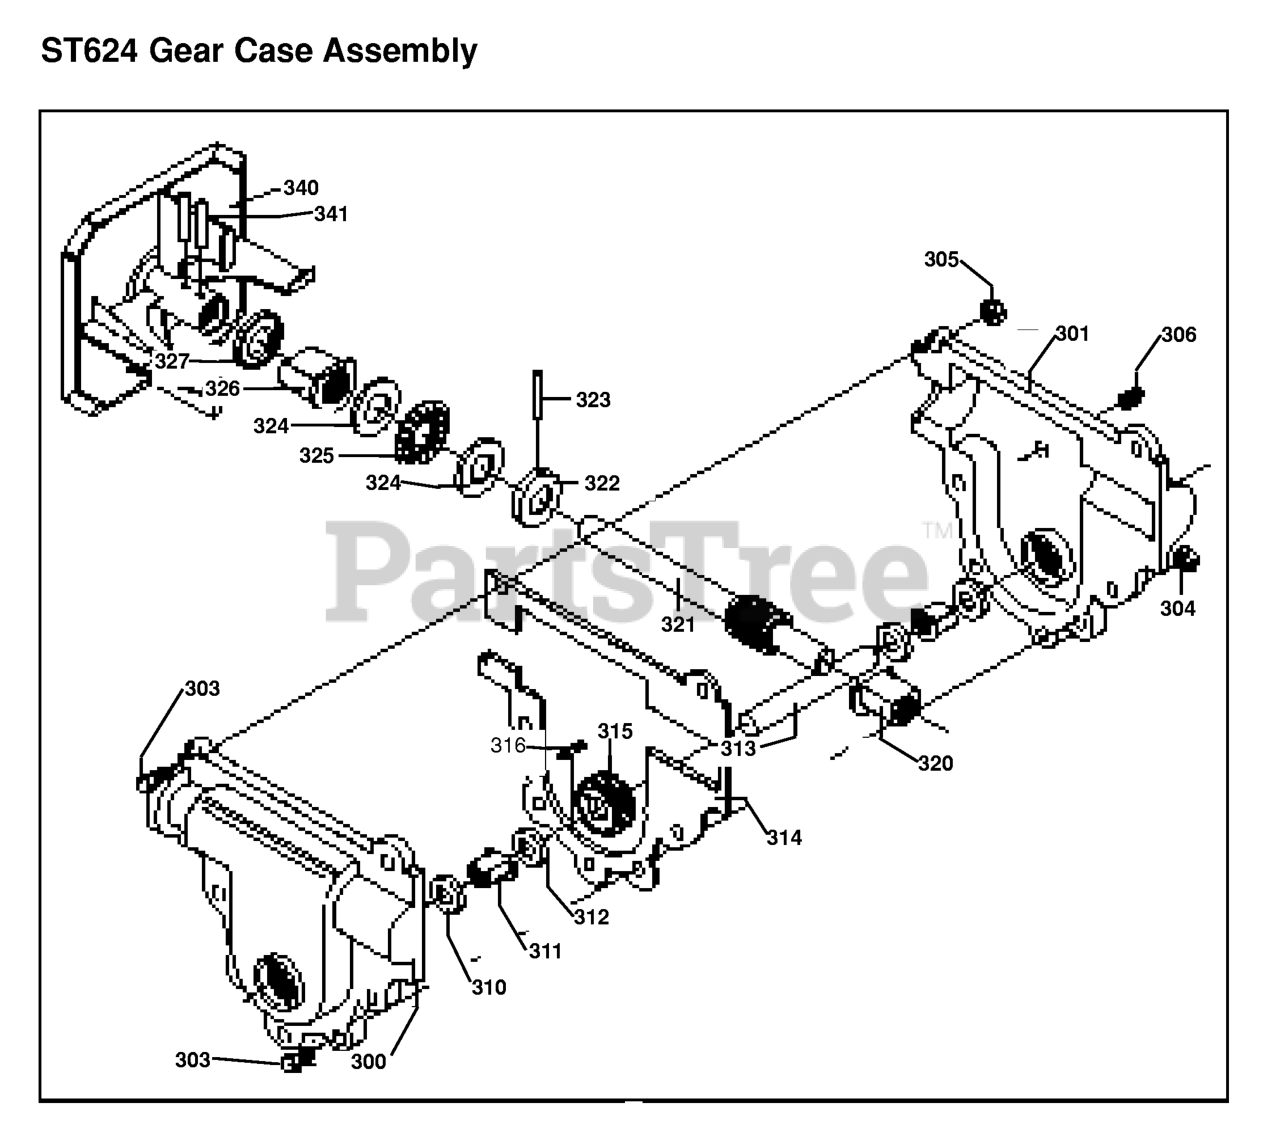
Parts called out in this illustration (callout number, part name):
300	GEAR CASE, RH
301	GEAR CASE, LH
303	SCREW, 1/4-20 X .75
304	NUT 1/4-20
305	NUT, 1/4-20 HEX KEPS
306	SCREW, 3/8-16X.50
310	SEAL, OIL, .75 X 1.19 X .25
311	BEARING, FLANGE
312	FLATWASHER
313	AUGER SHAFT
314	GASKET, GEAR CASE
315	GEAR, WORM
316	KEY, WOODRUFF
320	BRNG, FL .502IDX .752OD
321	SHAFT, WORM IMP INPUT
322	COLLAR, THRUST
323	PIN, SPRING
324	FLATWASHER
325	ROLLER BEARING
326	BEARING, FLANGE
327	SEAL, OIL, .75 X 1.19 X .25
340	IMPELLER, ASSY
341	PIN, SPRING
